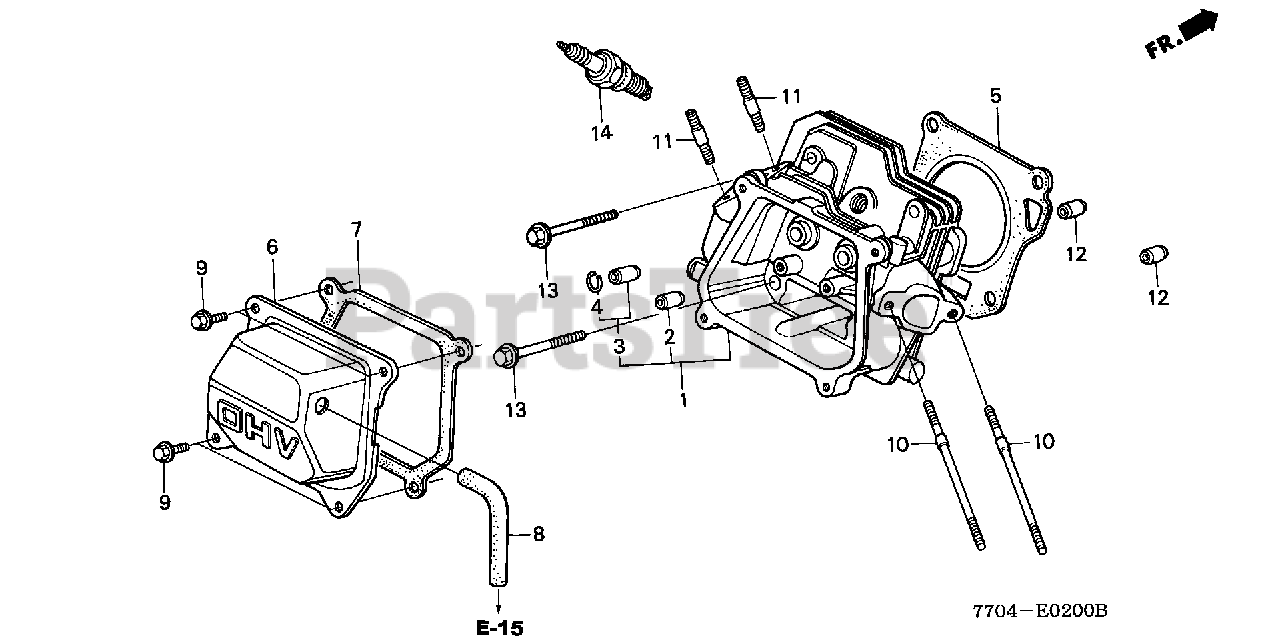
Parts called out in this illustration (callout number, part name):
1	CYLINDER HEAD
2	GUIDE, VALVE (OVER SIZE)
3	GUIDE, EX. VALVE (OVER SIZE)
4	CLIP, VALVE GUIDE
5	GASKET, CYLINDER HEAD
6	COVER, HEAD
7	GASKET, HEAD COVER
8	TUBE, BREATHER
9	BOLT, FLANGE (6X12) (CT200)
10	BOLT, STUD (6X112)
11	BOLT, STUD (8X32)
12	PIN, DOWEL (10X16)
13	BOLT, FLANGE (8X60)
14	SPARK PLUG (BPR5ES) (NGK)
14	SPARK PLUG (W16EPR-U) (DENSO)
14	SPARK PLUG (BPR6ES) (NGK)
14	SPARK PLUG (W20EPR-U) (DENSO)
